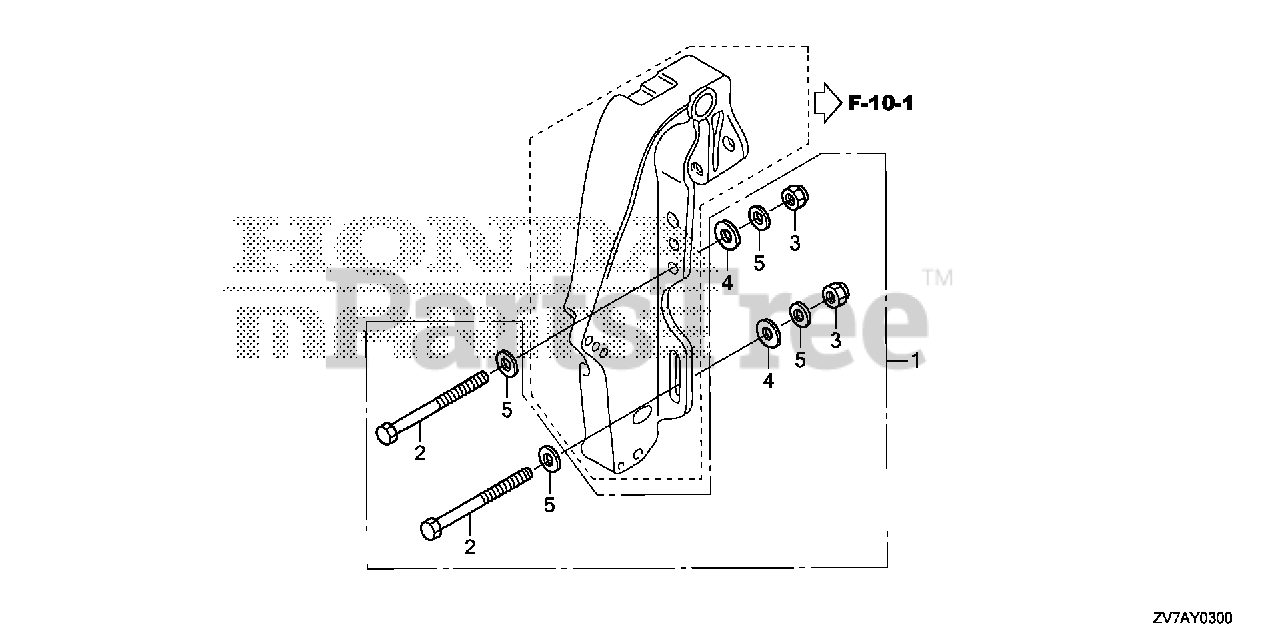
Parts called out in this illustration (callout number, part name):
1	INSTALLATION KIT, OUTBOARD
2	BOLT, HEX. (10X100)
3	NUT, SELF-LOCK (10MM)
4	WASHER, PLAIN (10MM)
5	WASHER, PLAIN (10MM)
